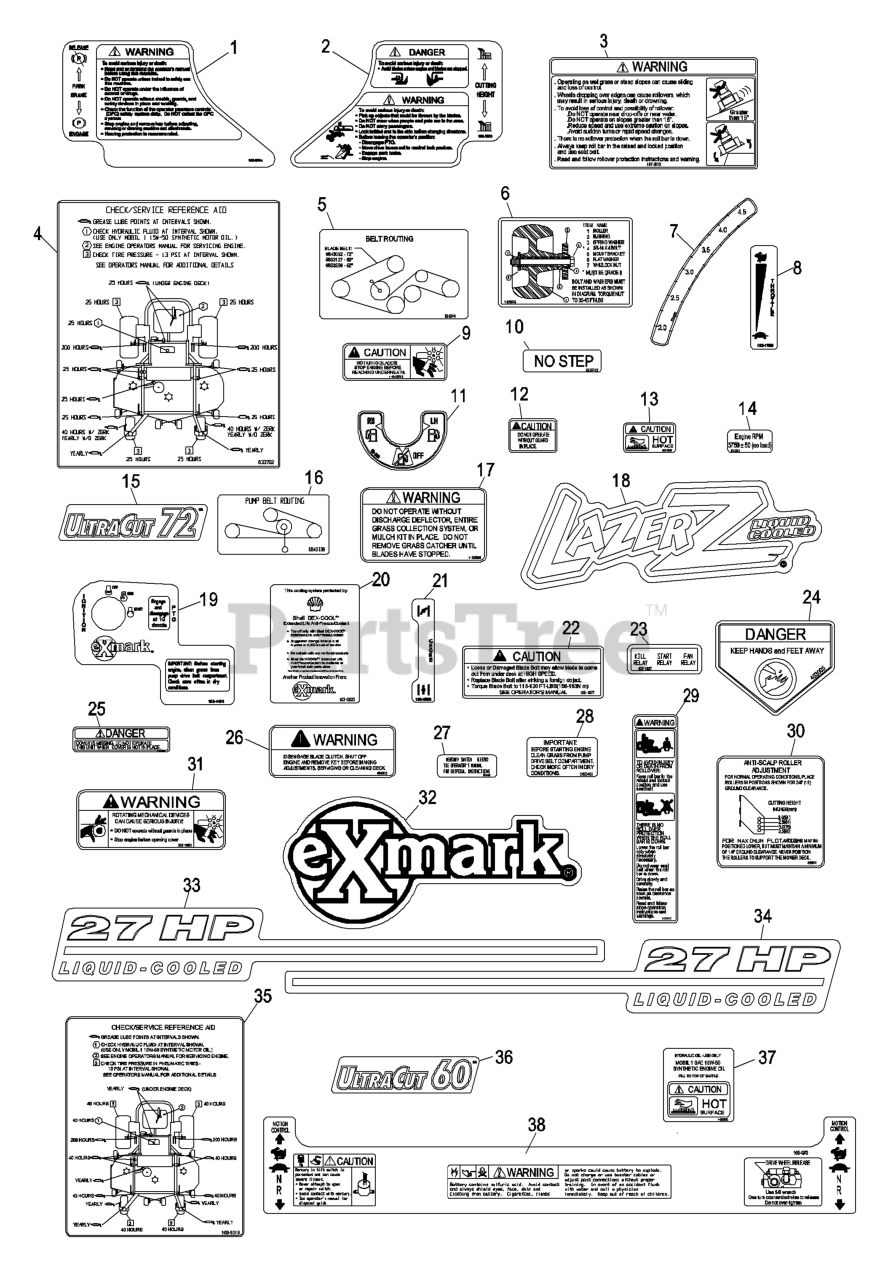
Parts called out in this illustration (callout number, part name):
1	DECAL,PARK BRAKE
2	DECAL,CUTTING HEIGHT
3	DECAL-WARNING
4	DECAL,CHECK/SERVICE
5	DECAL,BELT ROUTING
6	DECAL,ROLLER MOUNTING
7	DECAL-HEIGHT, DECK
8	DECAL,THROTTLE ONLY
9	DECAL-FAN, RADIATOR
10	DECAL,NO STEP
11	DECAL-VALVE, FUEL
12	DECAL-GUARD
13	DECAL-CAUTION
15	DECAL,ULTRACUT 72
16	DECAL-ROUTING, BELT
17	DECAL-WARNING, DISCHARGE
19	DECAL,IGNITION/PTO
20	DECAL,SHELL COOLANT
21	DECAL,CHOKE
22	DECAL,BOLT TORQUE
23	DECAL-RELAY
24	DECAL-DANGER
25	DECAL-COVER, MISSING
26	DECAL,WARNING
27	DECAL-SWITCH, MERCURY
28	DECAL-IMPORTANT
29	DECAL-WARNING, FOLDING RO
30	DECAL,ANTISCALP
31	DECAL-DEVICES, ROTATING
32	DECAL,EXMARK LOGO
33	DECAL,HOOD 27LC LH
35	DECAL,CHECK SERVICE LZ
36	DECAL,ULTRACUT 60
